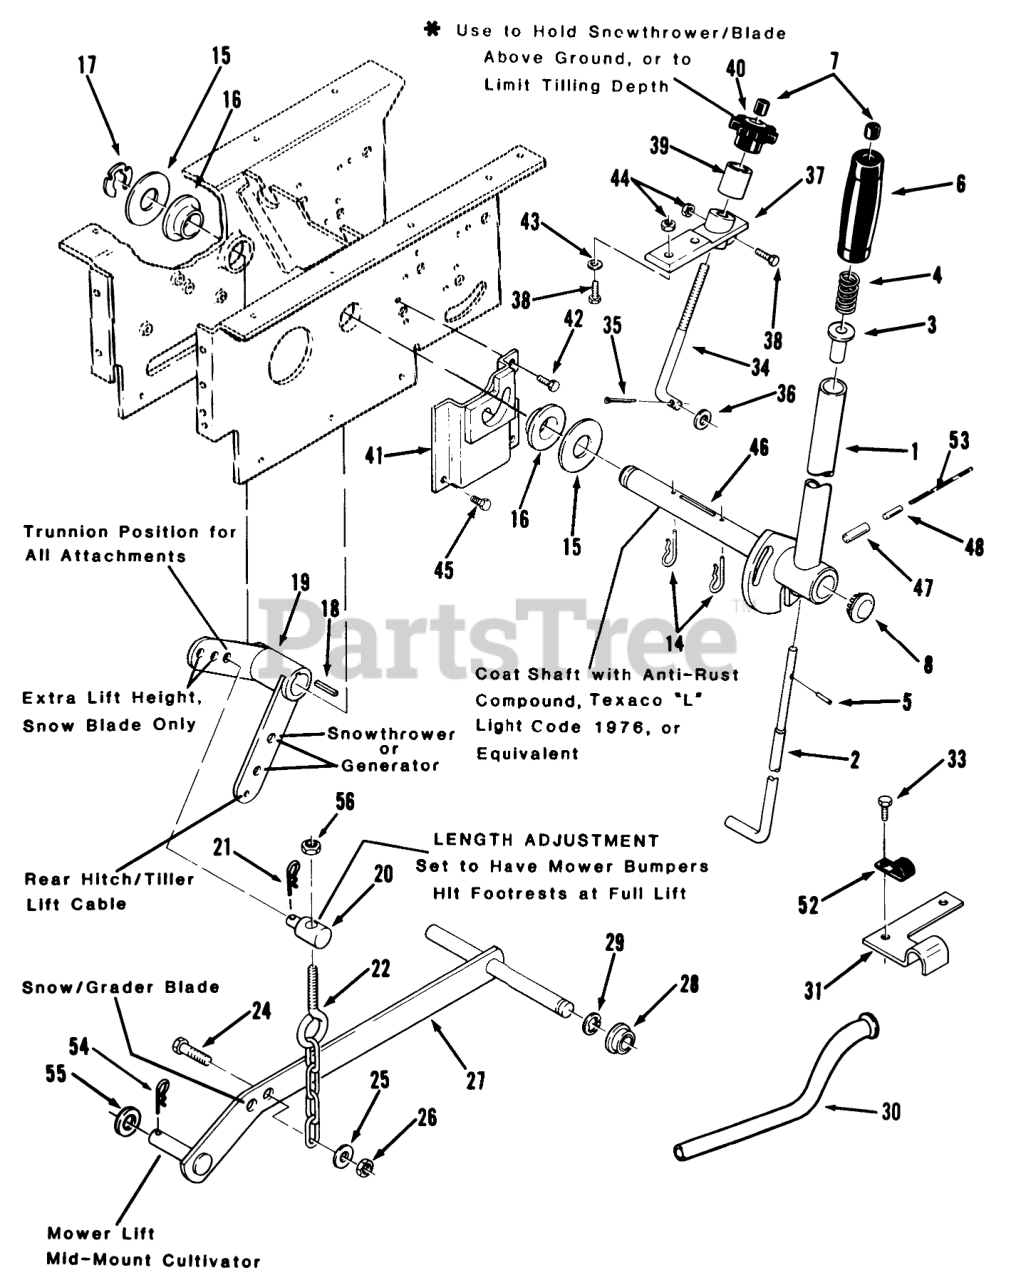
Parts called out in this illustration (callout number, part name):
1	Lift Lever (Includes Items 46, 47, 48)
2	ROD-LATCH LIFT
3	RETAINER-SPRING
4	SPRING-COMPRESSION
5	PIN-SPIROL
6	HANDGRIP
7	CAP-ROD, PLUNGER
8	PLUG
14	Pin-Cotter
15	WASHER
16	BEARING-FLANGE
17	Retainer
18	KEY-SQUARE
19	Bellcrank
20	TRUNNION-LIFT
21	Hairpin Cotter
22	CHAIN-LIFT
24	Bolt
25	WASHER 5/16 SAE
26	Nut
27	Bar-Lift
28	BUSHING
29	E Ring
30	TUBE ASSY COMPLET R
31	CLAMP-CONDUIT R
33	BOLT
34	ROD-HEIGHT CONTROL
35	Pop Rivet
36	Washer, 7/16
37	Casting
38	Bolt
39	Sleeve
40	KNOB-LIFT CONTROL
41	Latch Bracket
42	SCREW
43	WASHER 5/16 SAE
44	Nut
45	Bolt
46	SHAFT-LIFT LEVER
47	SPIROL PIN
48	Roll Pin
52	CLIP
53	Lock Wire
54	Hairpin Cotter
55	Washer
56	NUT
